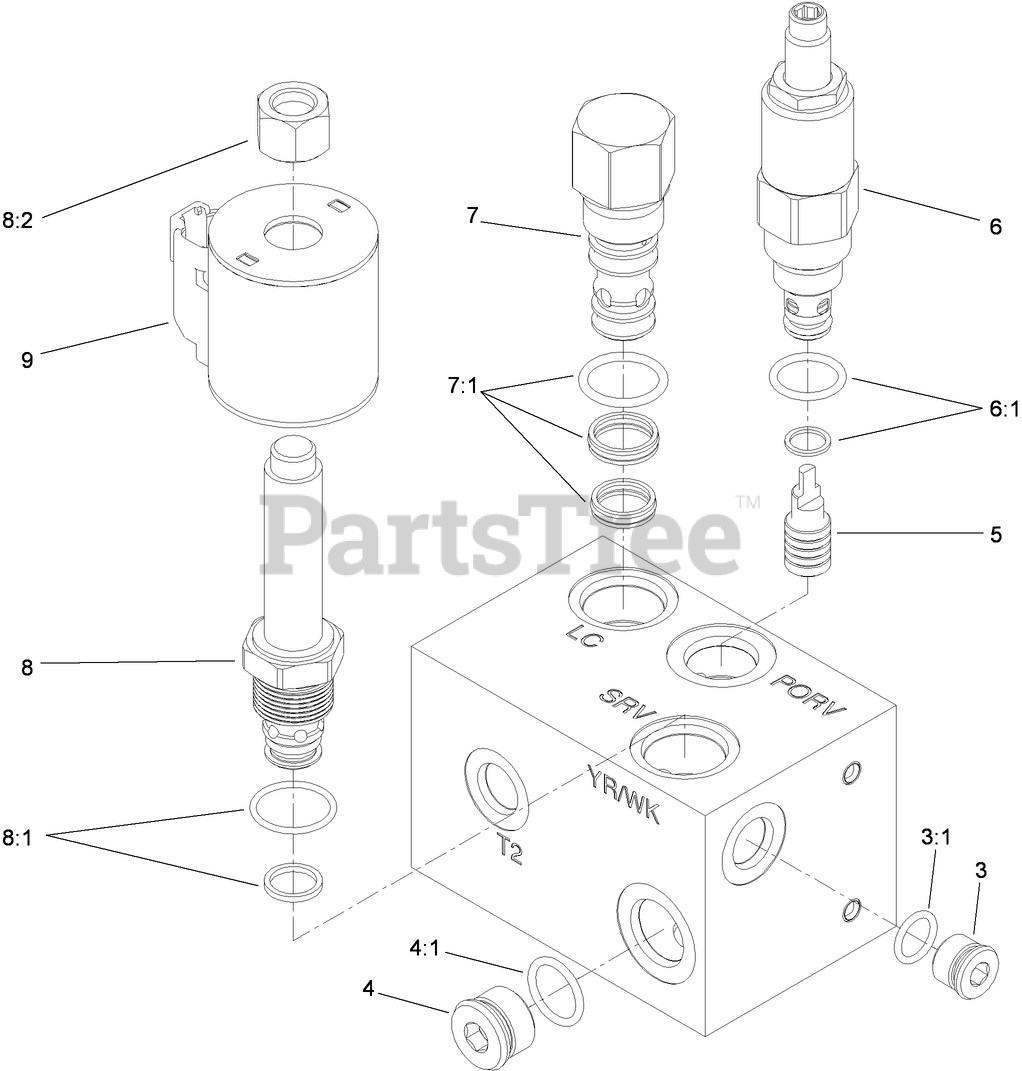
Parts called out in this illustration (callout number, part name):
3	PLUG-HYD
3:1	O-RING
4	PLUG-HYD
4:1	O-RING
5	PISTON-PILOT
6	VALVE-RELIEF
6:1	SEAL KIT
7	ELEMENT-LOGIC, VENTED
7:1	SEAL KIT
8	VALVE-RELIEF, SOLENOID
8:1	SEAL KIT
8:2	NUT-COIL
9	COIL-SOLENOID
